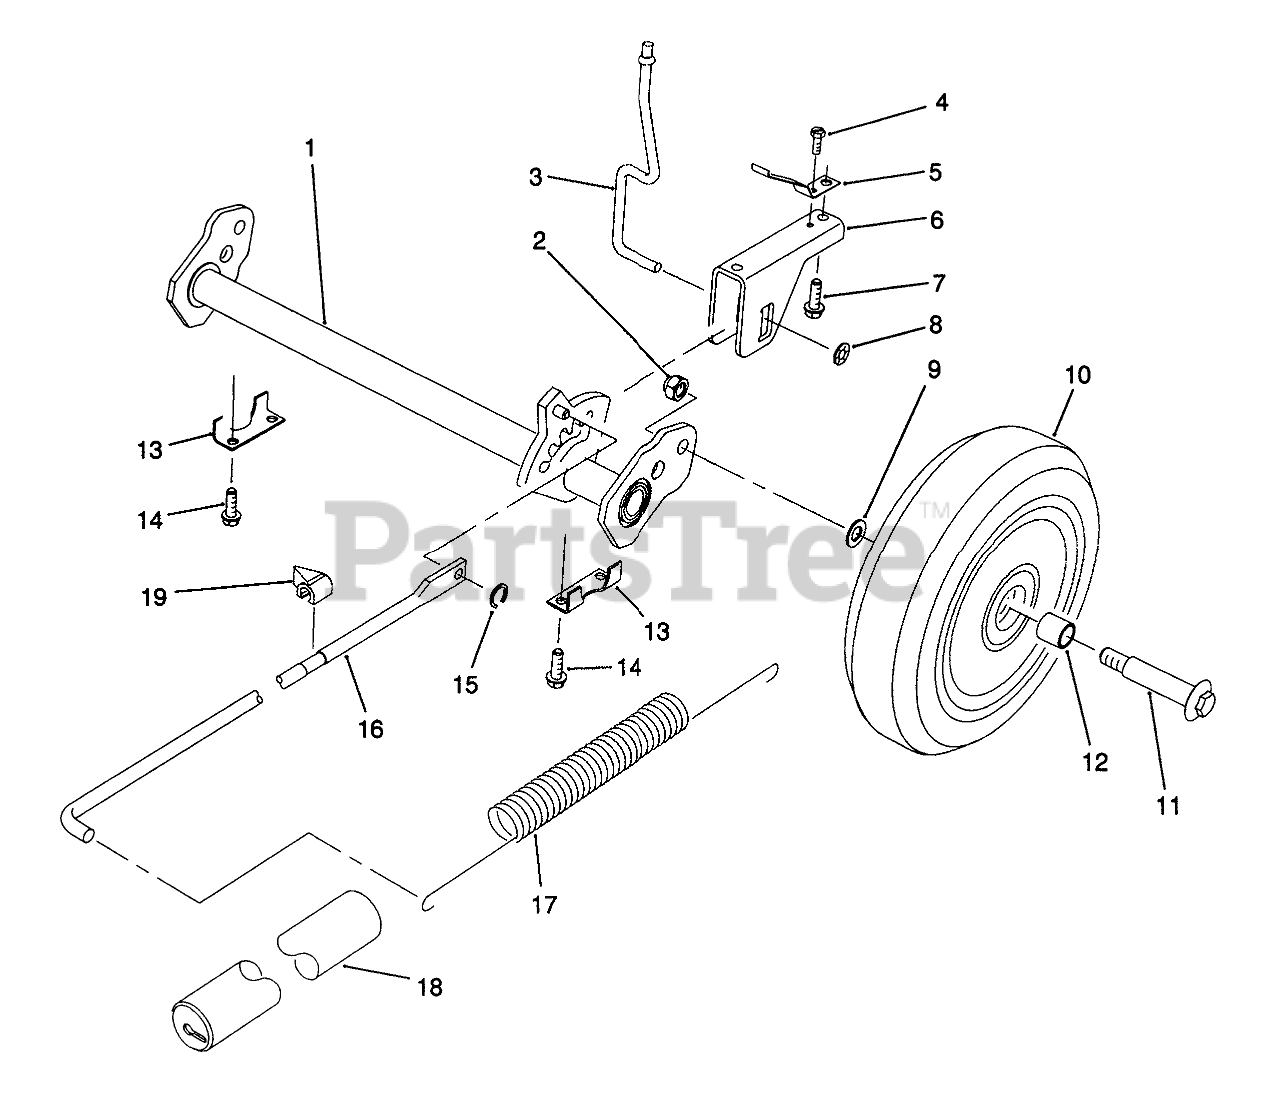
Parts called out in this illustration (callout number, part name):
1	PIVOT ARM REAR WA
2	Nut
3	TRIGGER ROD
4	SCREW 8 - 32 X 250
5	SPRING - TRIGGER RET
6	SADDLE - HOC
7	SCREW
8	PUSHNUT
9	WASHER
10	Wheel & Tire Assembly (Incl. Ref. #12)
11	BOLT-WHEEL
12	BUSHING
13	REAR SECURING PLATE
14	SCREW-HWHTF
15	GRIP RING
16	LINK ROD
17	SPRING-COUNTERBALANCE
18	COVER-SPRING
19	INDICATOR-HEIGHT OF CUT
